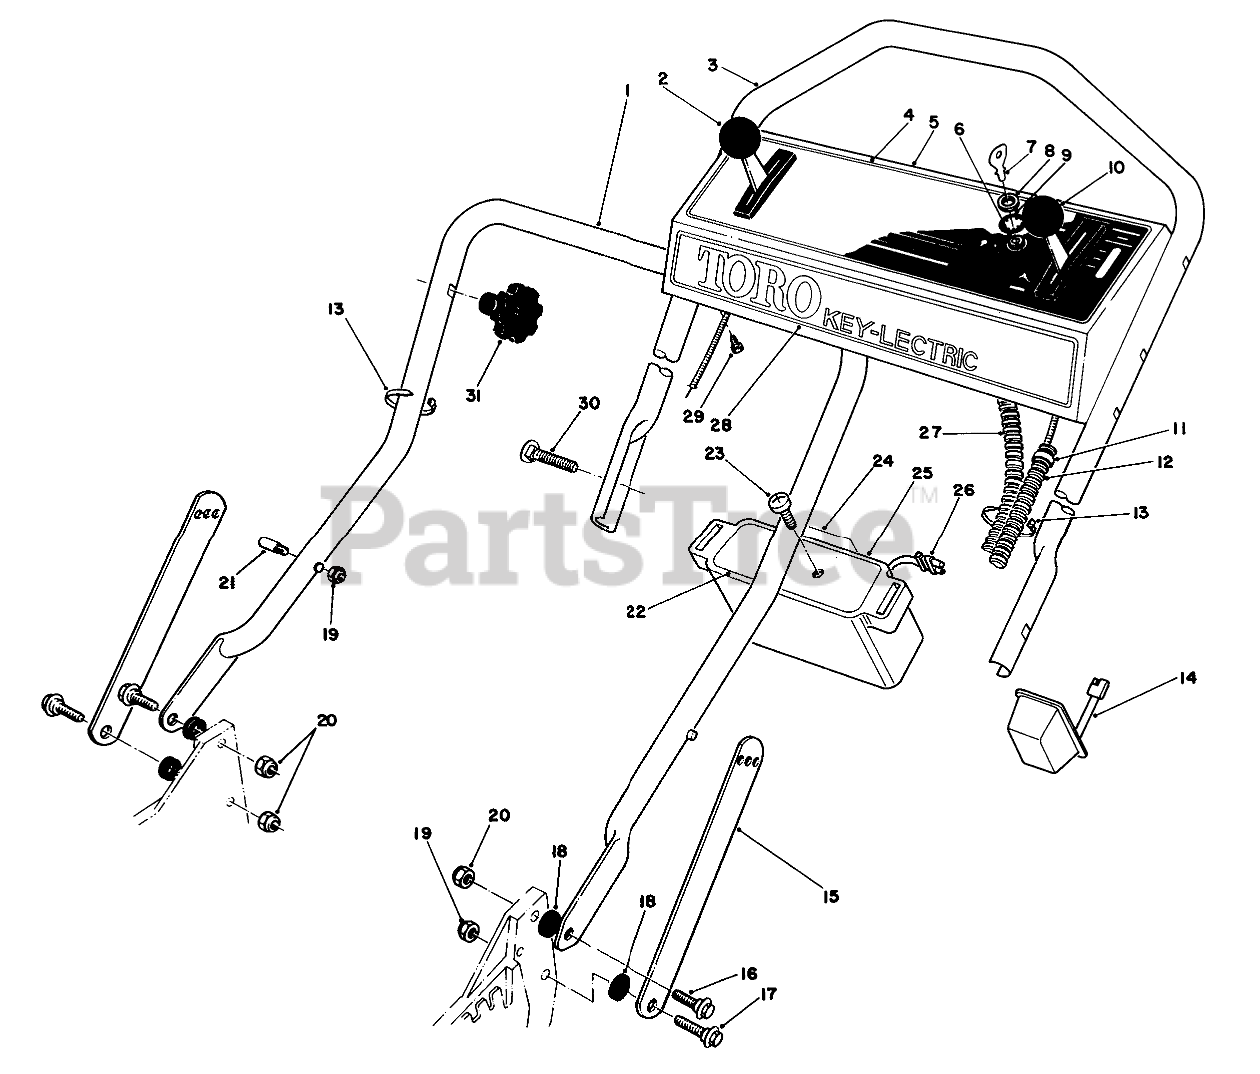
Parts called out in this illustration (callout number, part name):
1	Handle-Lower
2	GROUND SPEED CONTROL
3	Handle-Upper
4	Decal-Instruction Panel
5	Control Panel (Incl. Ref. #4)
6	Switch-Starter (Incl. Ref. #8 & 9)
7	Key
8	NUT-HH
9	WASHER-TOOTH, INTERNAL
10	SERVICE THROTTLE CONTRO
11	FITTING-RING
12	CONTROL CABLE COVER
13	TIE-CABLE
14	Charger
15	Handle Latch
16	SCREW-SHOULDER
17	SCREW-SHOULDER
18	SPACER
19	NUT-LOCK, NI
20	NUT-LOCK, NI
21	HANDLE PIN
22	BATTERY COVER
24	Decal
25	Battery Case
26	LEAD WIRE ASM
27	WIRE HARNESS
28	Decal-Toro
29	SCREW-HWHTF
30	5/16-18 X 2 HNDLE SCREW
